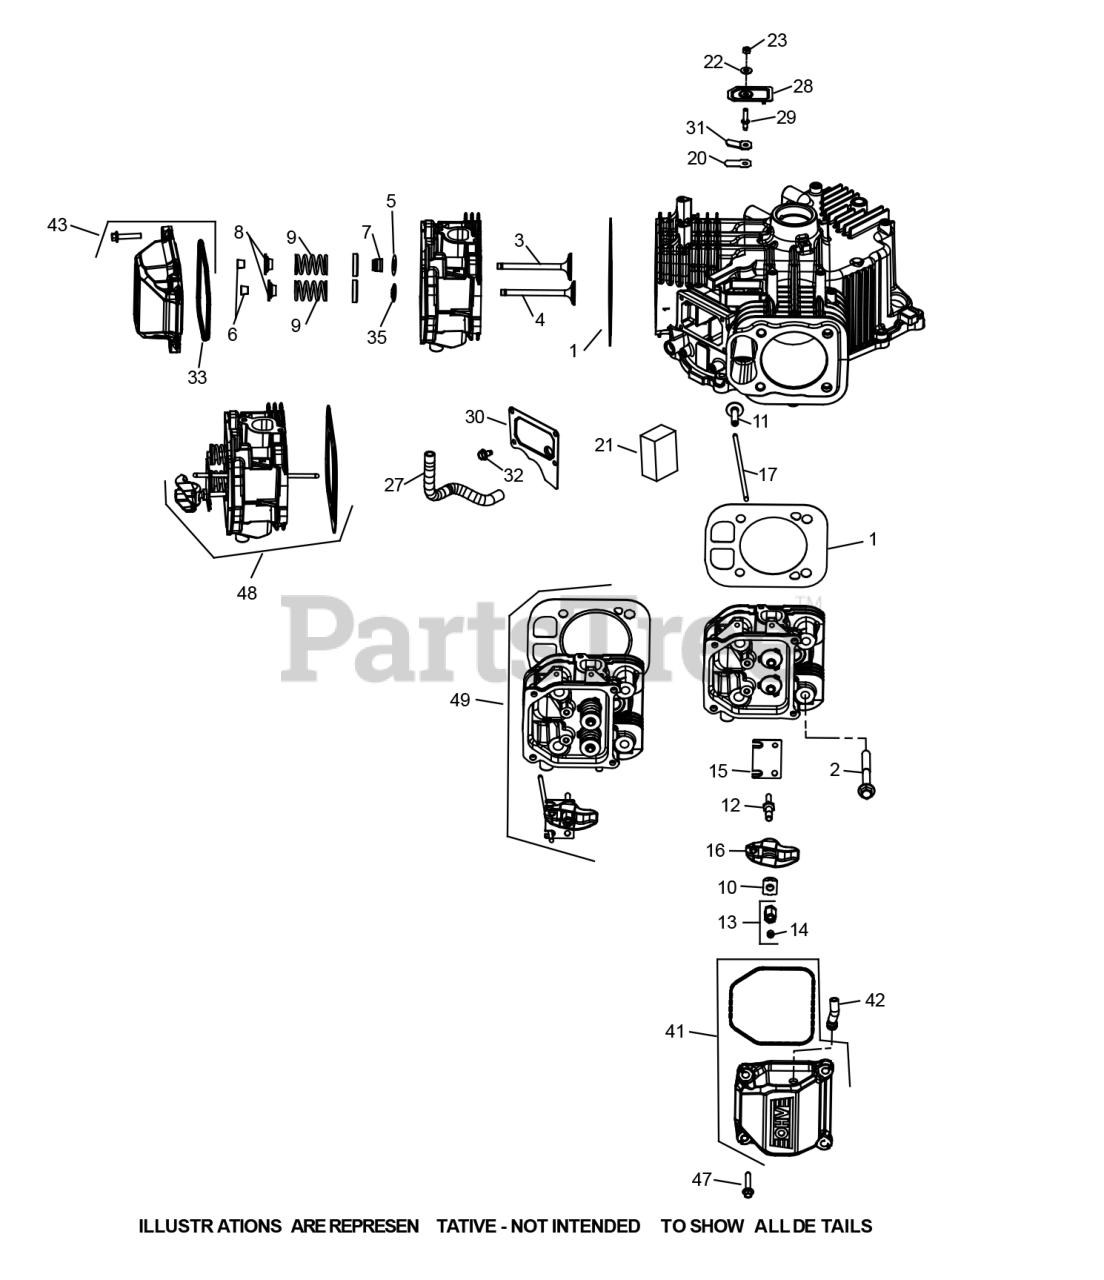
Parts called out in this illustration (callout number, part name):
1	GASKET KIT-CYL HEA
2	SCREW-HEX FLG M10X1.5-6X90
3	INTAKE VALVE .25
4	EXHAUST VALVE
4	EXHAUST VALVE .25
6	KIT-RETAINER
7	VALVE STEM SEAL
8	VALVE CAP SPRING
10	PIVOT- ROCKER ARM
11	TAPPET-PUSH ROD
13	NUT ASSEMBLY-ROCKER
20	BREATHER REED
21	BREATHER FILTER
22	SEALING WASHER
27	BREATHER HOSE
28	COVER-BREATHER REED
29	STUD-BRETHR REED C
30	COVER-BREATHER FILTE
31	RETAINER-BREATHER
33	O-RING VLV CVR
35	VALVE GUIDE RETAINER
41	KIT-ROCKER COVER
42	HOSE KIT-FUEL PUMP
43	COVER KIT-ROCKER
47	SCREW-HEX FLANGE M6x31.625
48	CYLINDER HEAD #1
49	CYLINDER HEAD #2
